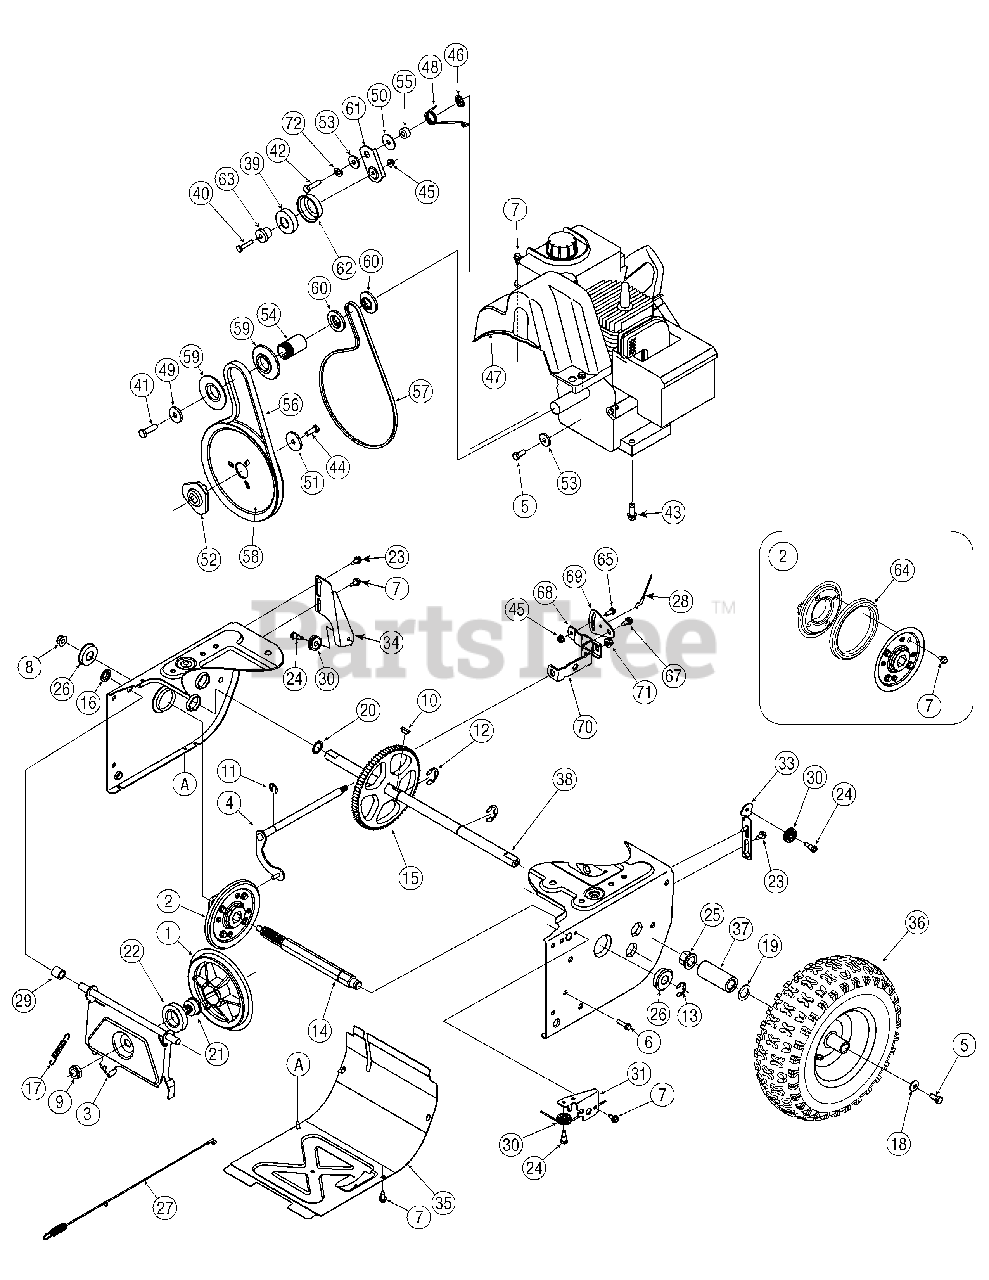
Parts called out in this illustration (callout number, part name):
1	Disc, Friction Wheel
2	Friction Wheel Assembly, 5.5 O.D.
4	Shift Assembly, Rod
5	Hex Screw, 5/16-24, .750, Gr5
6	Screw, 1/4-20, 1.000
7	Screw, 1/4-14 x .625
8	Nut, Flange Lock, 3/8-16, Nylon
9	Nut, Jam Lock, 5/8-18, Gr5, Nylon
10	Key, Hi Pro, 3/16 x 3/4
11	E-ring, .500 Dia.
12	E-ring, Retaining, .875 Dia.
13	E-ring, .750 Dia.
14	Hex Shaft, .8125, 7-Tooth
15	Gear, 80-Tooth
16	Speed Nut, .500
17	Extension Spring
18	Washer, Bell, .340 x .872 x .060
19	Washer, Flat, .793 x 1.24 x .060
20	Washer, Flat, .75 x 1.00 x .060
21	Pin, Friction Disc
22	Ball Bearing, 30 x 55 x 13
23	Screw, Shoulder, .37 x .105, 1/4-20
24	Screw, 1/4-28, .375
25	Bearing, Hex Flange x .75
26	Bearing, Ball, 17 x 40 x 12
27	Clutch Cable, Wheel, 44.95"
28	Clutch Cable, Auger, 47.23"
29	Spacer, .508 ID x .75 OD x .68
30	Roller, Cable
36	Wheel Assembly - 15" x 5"
36	Valve Only
36	Rim Only
37	Spacer, 1.25 x .75 x 3.0
38	Axle, .75 x 22"
39	Ball Bearing
40	Hex Screw, 1/4-20, 1.25, Gr5
41	Hex Screw, 3/8-24, 1.25, Gr8
42	Hex Screw, 5/16-24, 1.25, Gr5
43	Screw, Sems, 3/8-16, 1.00
44	Hex Screw, 5/16-24, .875, Gr8
45	Nut, Flange Lock, 1/4-20, Nylon
46	Nut, Push-on, .25 Dia.
47	Cover, Belt
48	Spring, Torsion, .850 ID x .354
49	Washer, Flat, .406 x 1.25 x .157
50	Washer, Flat, .330 x 1.25 x .06
51	Washer, Flat, .34 x 1.50 x .150
52	Pulley, Adap, .75 Dia W/dd
53	Spacer, Shoulder
54	Spacer, .875 ID x 1.185 OD
55	Spacer, .340 x .750 x .360
56	Belt, Auger Drive
57	Belt, Wheel Drive
58	Pulley, Auger Drive, 8.1 x .5
59	Pulley, Half, V x 2.600 OD
60	Pulley, Half, 1/4-V x 1.5 OD
61	Idler Bracket, Wheel Drive
62	Sleeve, Bearing Idler
63	Spacer, Shoulder, .26 x .79 x .538
64	Rubber, Friction Wheel, 5.5 OD
65	Hex Screw, 1/4-20, .620, Gr5
66	Spring, Torsion, .750 ID x .968
67	Screw, Shoulder, .37 x .105, 1/4-20
68	Bracket, Shift Spacer
71	Nut, Flange Lock, 5/16-18, Nylon
72	Washer, Lock, 5/16
